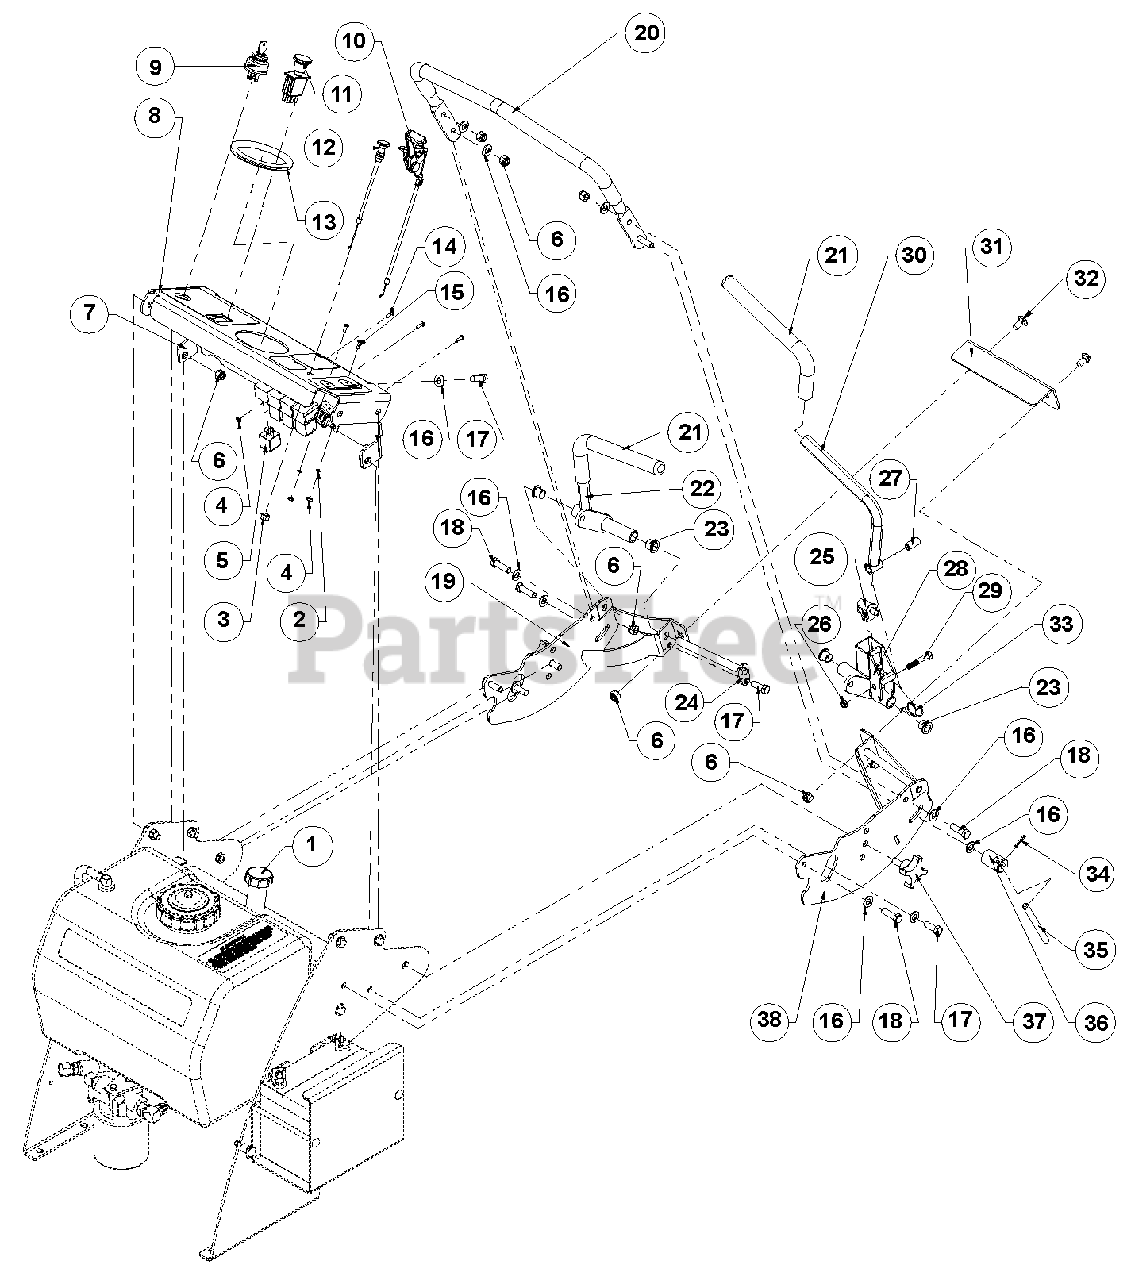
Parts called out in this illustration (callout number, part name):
1	Cap, Oil Fill Breather
2	Washer, #8 Medium Spring Lock
3	Nut, .38-24 Standard Hex
4	Nut, 8-32 Standard Hex
5	Relay, ISO Mini Electric
6	Locknut, .38-16 Nyloc
7	Weldment, Handle Brace
8	Console, Loop Handle Hydro
9	Switch, Key- 3 Position
10	Cable, Throtle 49.5"
11	Switch, PTO Engagement
12	Cable, Choke 48.0"
13	Trim, Rubber Edge 12"
14	Screw, 8-32 x .50
15	Screw, 8-32 x .500 Round Head Machine
16	Washer, .406 x .813 x .065 Flat
17	Bolt, .38-16 x 1.00 Hex 5
18	Bolt, .38-16 x 1.25 Hex 5
19	Weldment, Right Hand Control Mount
20	Handle, Loop Hydro
21	Grip, Control
22	Weldment, Right Hand Drive Lever
23	Bearing, Flange .500 x .625 x .500
24	Weldment, Pin and Lock
25	Switch, Seat Overide
26	Locknut, .3125-18 Nyloc
27	Spacer, .500 x .330 x .980
28	Weldment, Left Hand Handle Mount
29	Bolt, .3125-18 x 1.75 Hex 5
30	Weldment, Left Hand Drive Lever
31	Drive Arm Back Plate
32	Bolt, .38-16 x .750 Round Head Square Neck
33	Spring, Torque 1.00 x .062
34	Pin, Spring
35	Lever, Lock Y Assembly
36	Lever, Lock Y Assembly
37	Knob, Star .38-16 x 1.00
38	Weldment, Left Hand Control Mount
